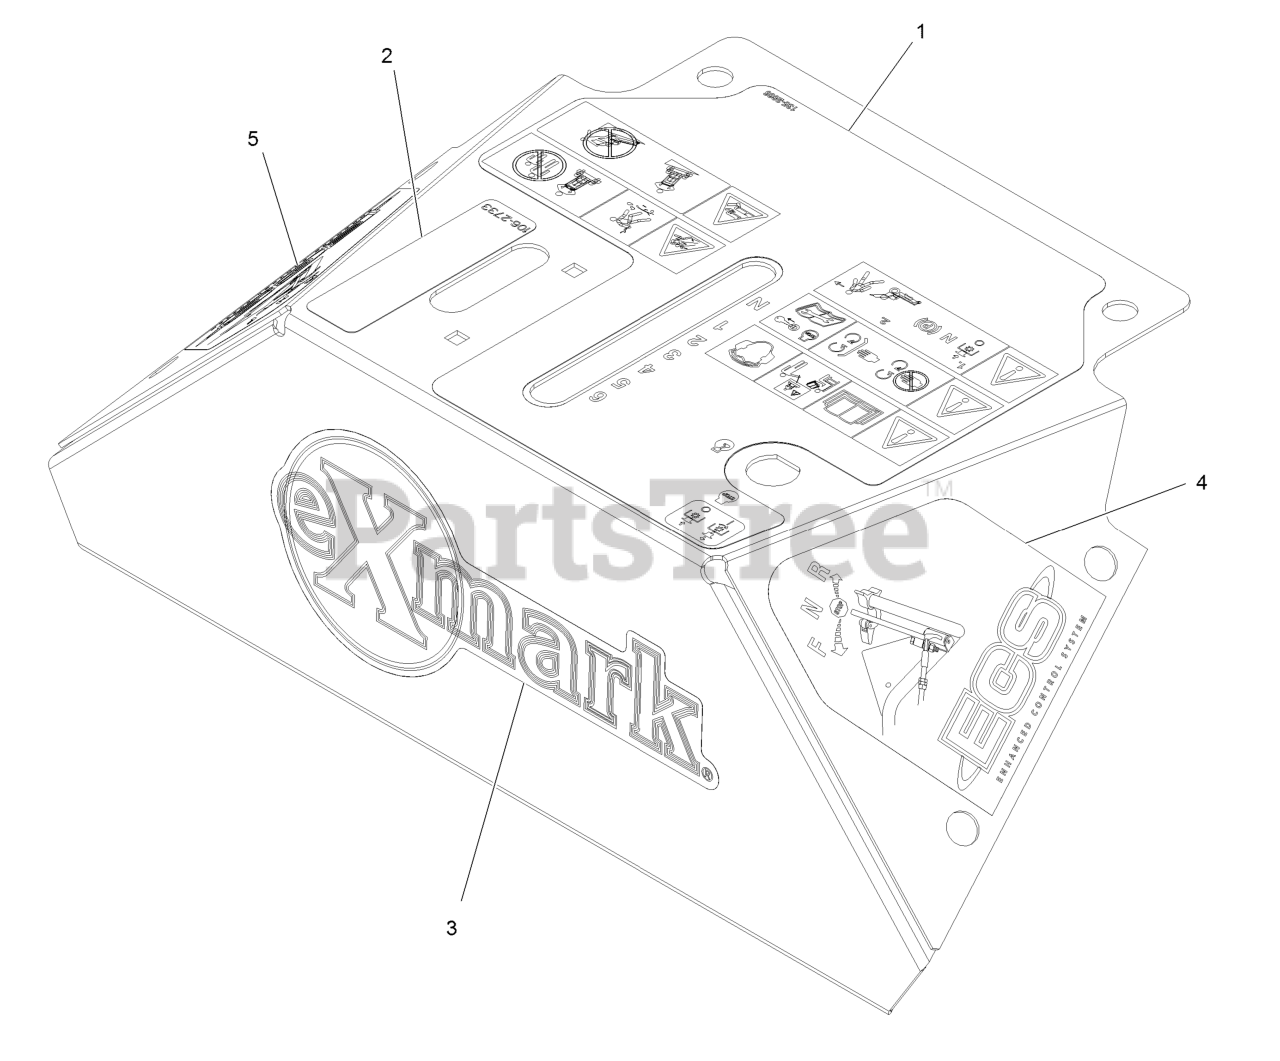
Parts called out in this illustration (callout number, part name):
1	Decal-Console
2	Decal-Throttle
3	Decal, Exmark Logo
4	Decal, Ecs Instruction LH
5	Decal, Ecs Instruction RH
